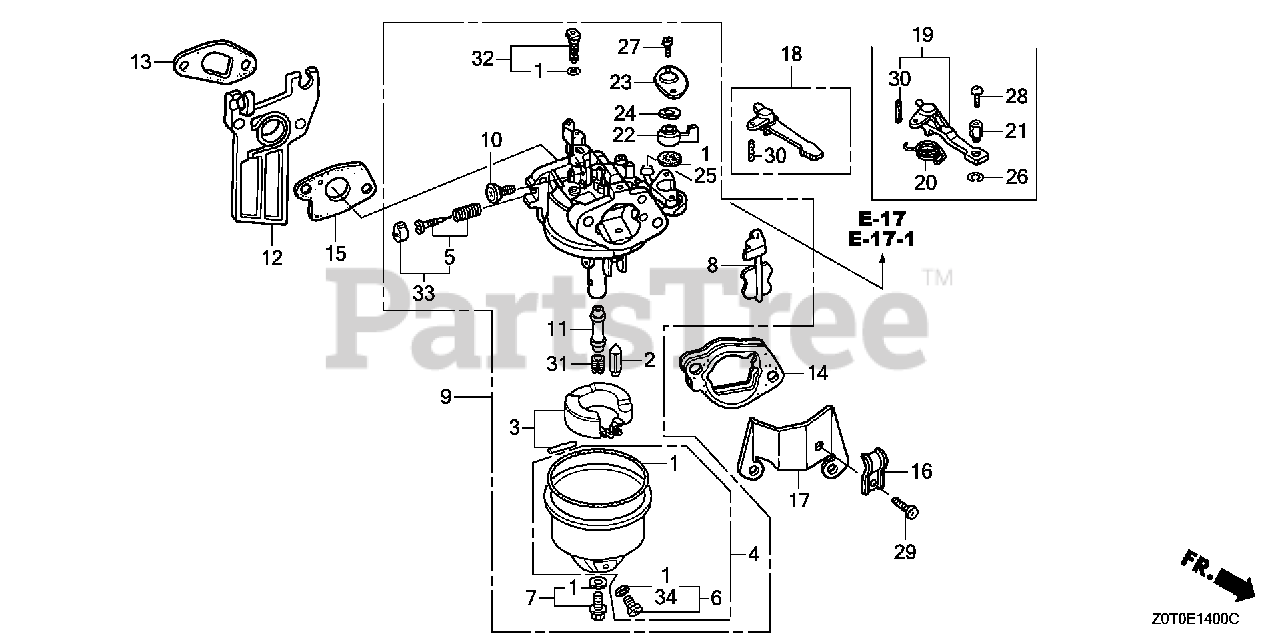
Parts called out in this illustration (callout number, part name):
1	GASKET SET
2	VALVE SET, FLOAT (SEAT NOT INCLUDED)
3	FLOAT SET (CARBURETOR NO.)
4	CHAMBER SET, FLOAT
6	SCREW SET, DRAIN
9	CARBURETOR ASSY. (BE66U A)
10	SCREW, THROTTLE STOP
11	NOZZLE, MAIN
12	INSULATOR, CARBURETOR
13	GASKET, INSULATOR
14	SPACER, CARBURETOR
15	GASKET, CARBURETOR
18	LEVER, CHOKE (STD)
22	LEVER, PETCOCK
23	PLATE, LEVER SETTING
24	SPRING, PETCOCK LEVER
25	GASKET, PETCOCK
27	SCREW, PAN (3X6)
30	PIN, SPRING (2X12)
31	JET, MAIN (#62)
31	JET, MAIN (#65)
31	JET, MAIN (#68)
32	JET SET, PILOT (#35) (CARBURETOR NO.)
33	SCREW SET, PILOT (CARBURETOR NO.)
